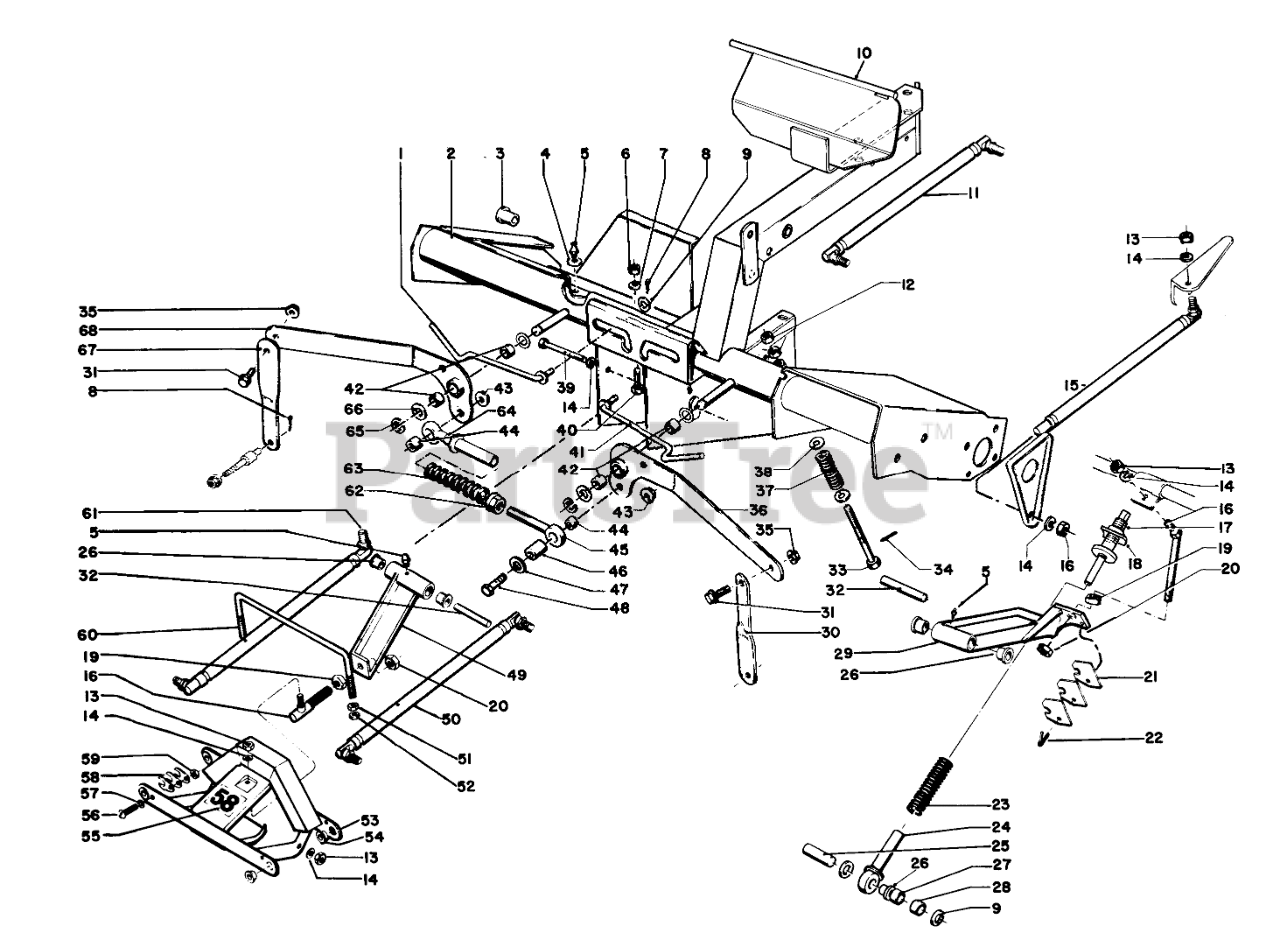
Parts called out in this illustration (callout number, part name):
1	Link-Transport R.H.
2	Main Frame (Incl. Ref. #3)
3	3/4IDX1LG FLANGE BSHG
4	WASHER-LOCK
5	FITTING-GREASE
6	NUT-HEX
7	WASHER-LOCK
8	PIN-COTTER
9	WASHER-FLAT
10	Mounting Plate
11	Ball Joint Assembly
12	NUT-HEX
13	NUT-HEX
14	WASHER-LOCK
15	Ball Joint Assembly
16	BALL JOINT
17	ANCHOR, SPRING COBAL
18	ADJUSTING NUT
19	NUT-LOCK, NI
20	NUT-JAM
22	PIN-COTTER
23	COMPRESSION SPRING
24	GUIDE & BUSHING WA
25	Spacer
26	BUSHING-FLANGE
27	SPLIT SPACER
28	Spacer
29	Mount-Counterbalance (Incl. Ref. #26)
30	Link-L.H.
31	SHOULDER BOLT
32	SPLIT SPACER
33	Screw
34	PIN-ROLL, SLOTTED
35	NUT-LOCK
36	Arm (Incl. Ref. #42)
37	SPRING
38	WASHER-PLAIN
39	SCREW-HH
40	SCREW-HH
41	Link-Transport L.H.
42	BUSHING
43	NUT-KEPS
44	BUSHING
45	Yoke (Incl. Ref. #44)
46	Spacer
47	WASHER-FLAT
48	SCREW-HH
49	Hitch-Yoke (Incl. Ref. #26)
50	BALL JOINT ASM
51	NUT-HEX
52	NUT-LOCK
53	Intermediate Frame (Incl. Ref. #54)
54	BUSHING-FLANGE
55	Decal
56	10-24 X 7/8 RND HD MS
57	SPACER
58	FRONT SIDE SHIM
59	NUT-LOCK, NI
60	Spring Stabilizer
61	BALL JOINT ASM
62	NUT-LOCK, FLANGE
63	Spring
64	Yoke (Incl. Ref. #44)
65	RING-RETAINING, EXTERNAL
66	WASHER-FLAT
67	Link R.H.
68	Arm (Incl. Ref. #42)
